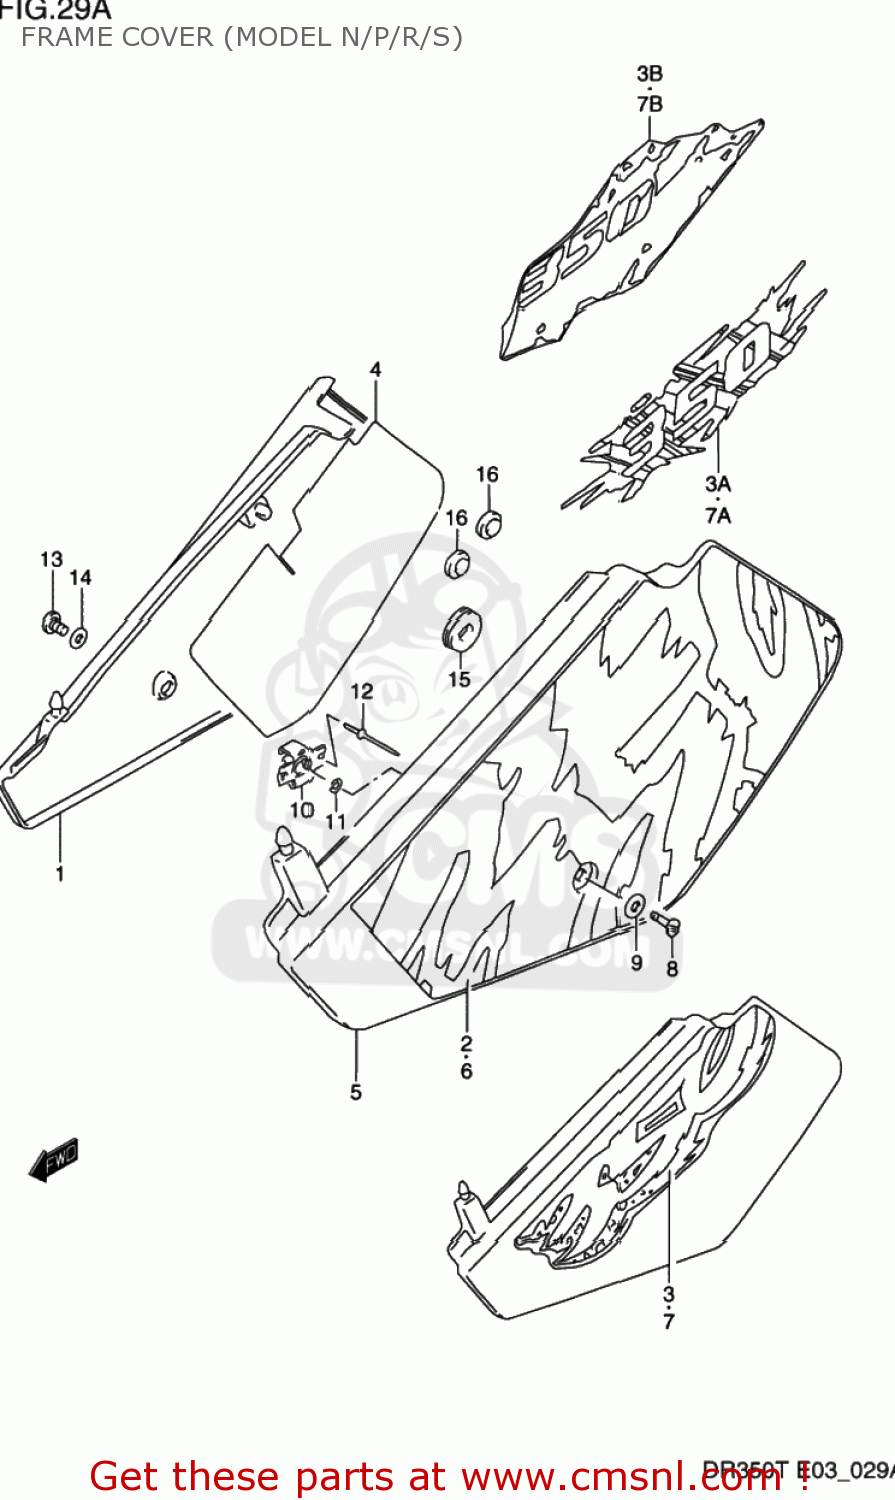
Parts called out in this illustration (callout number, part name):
1	COVER,FRAME,R(WHITE)
2	TAPE,FRAME COVER,RIGHT
3	EMBLEM,FRAME COVER,R
3A	EMBLEM,FRAME COVER
3B	TAPE,FRAME COVER,R
4	SHIELD,FRAME COVER,R
5	COVER,FRAME,L(WHITE)
6	TAPE,FRAME COVER,LEFT
7	EMBLEM,FRAME COVER,LEFT
7A	EMBLEM,FRAME COVER
7B	TAPE,FRAME COVER,LEFT
8	STUD,FRAME COVER,LEFT
9	WASHER(7.2X18X1.6)
10	RETAINER,FRAME COVER STUD,L
11	PLATE,FITING
12	RIVET
13	SCREW
14	WASHER
15	CUSHION
16	CUSHION
